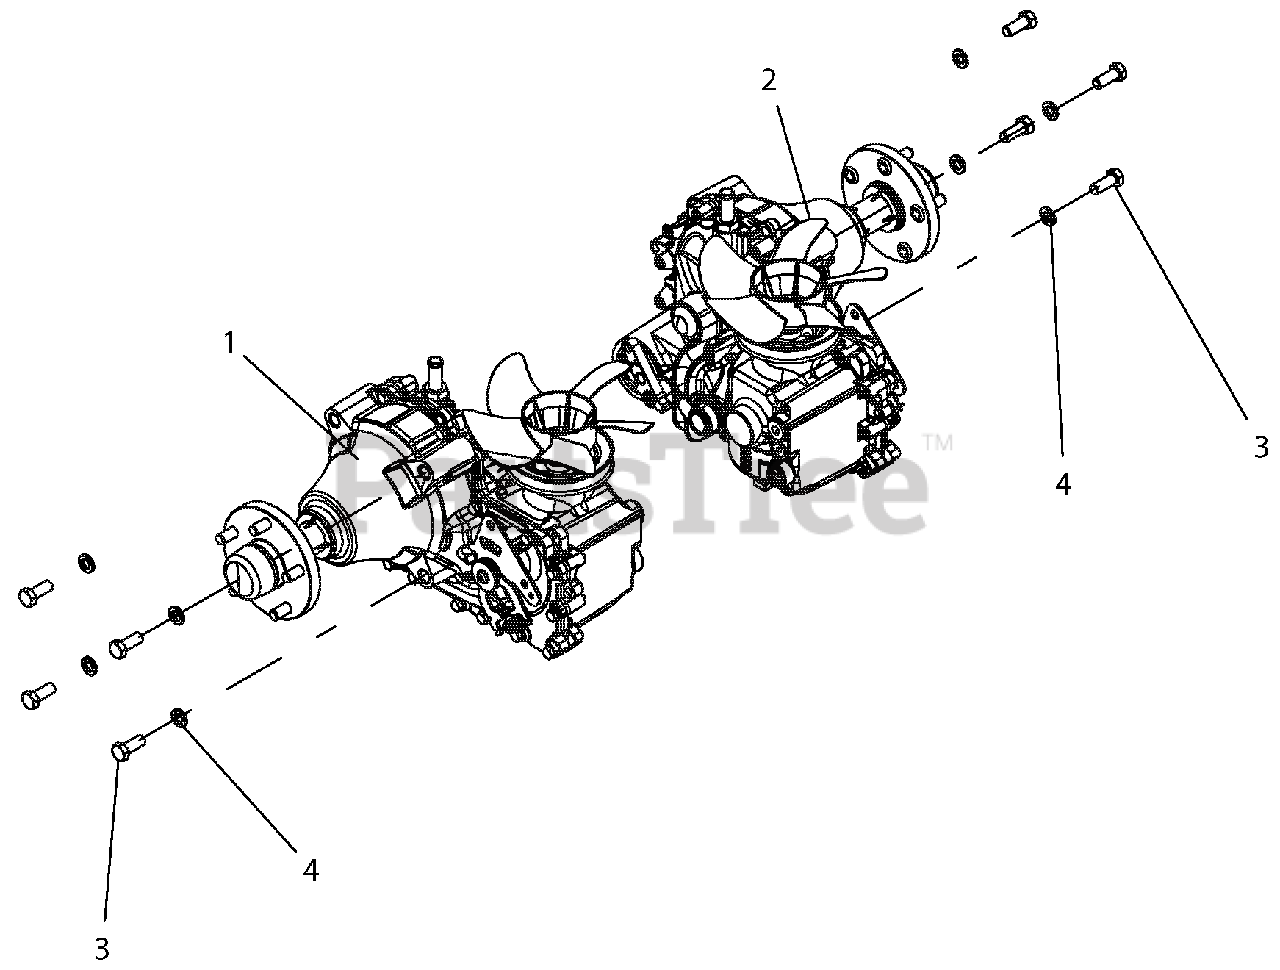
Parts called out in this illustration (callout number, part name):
1	TRANS, R.H. HG ZT-5400
2	TRANS, LH HG ZT-5400
3	BLT-HEX .50-13X1.25 GR5 YWZC
4	WSHR-LK .50X.125 REG YWZC
